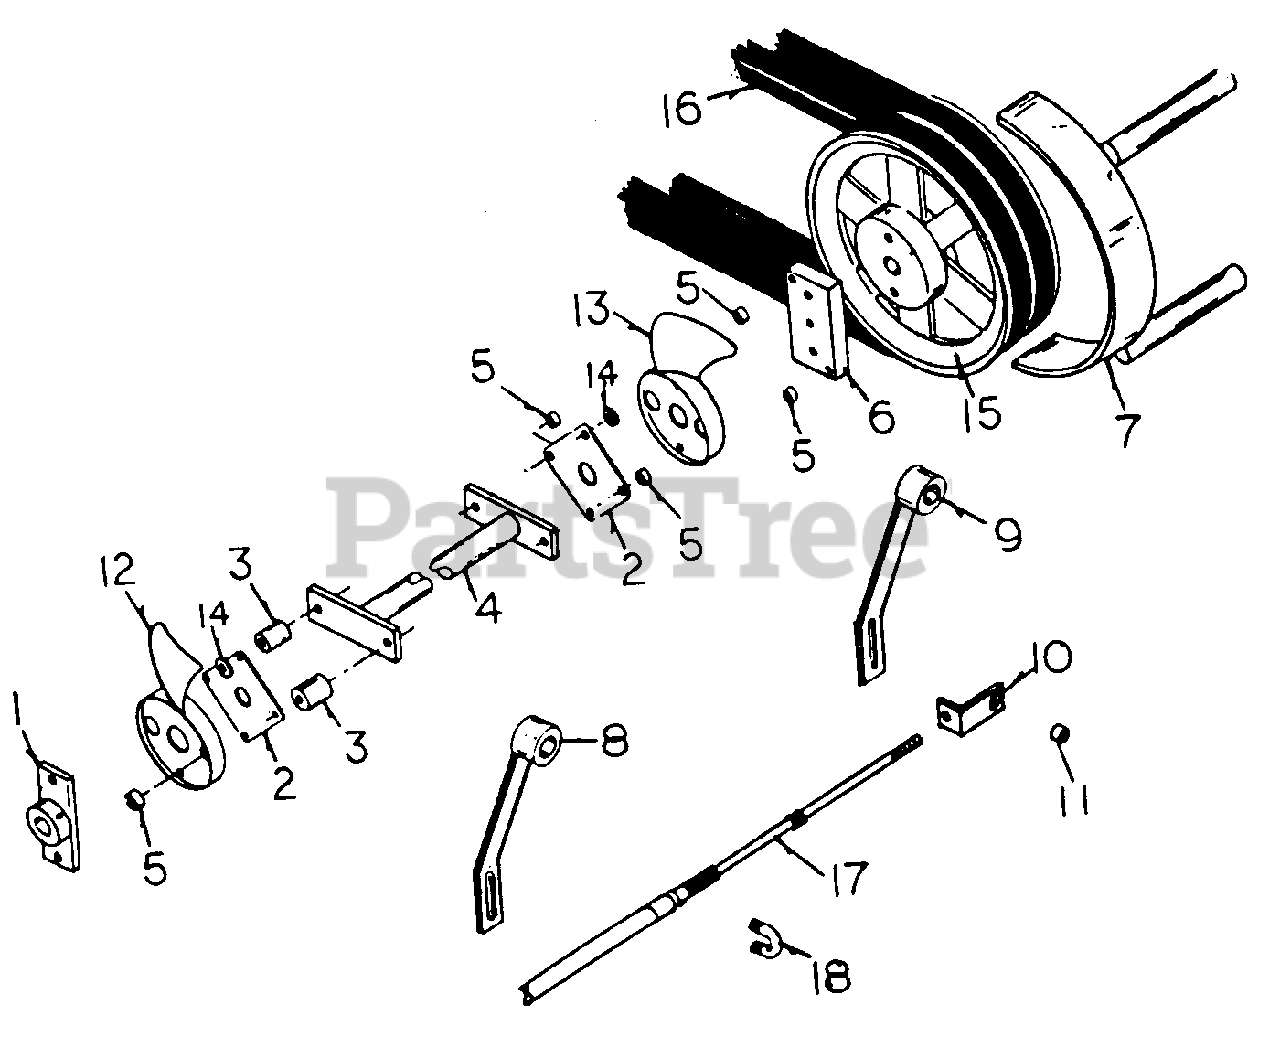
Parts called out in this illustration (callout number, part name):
1	Hub w/Drive Plate
2	Drive Plate
6	Cross Bar Block
7	Transmisslon Belt Retainer
8	Transmisslon Arm, LH
9	Transmission Arm, RH
10	Steering Cable Ends
11	Steerlng Cable Ends Bushing
17	Steering Cable
